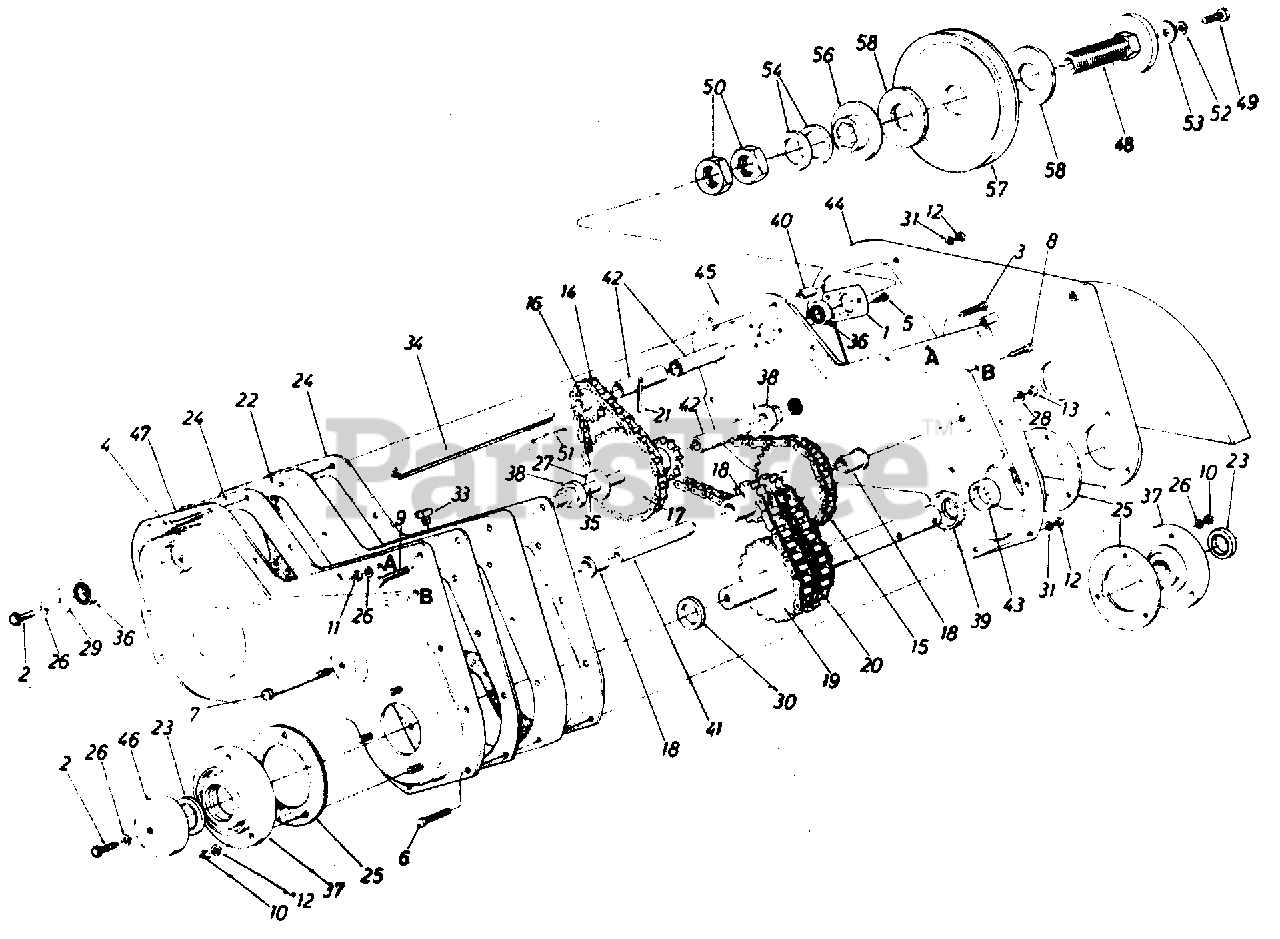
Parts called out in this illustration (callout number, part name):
1	Bearing Housing 1-3/8" Dia.
2	Hex Bolt 5/16-18 x .88"
3	Hex Bolt 5/16-18 x 1.5" Lg.
4	Hex Bolt 1/4-20 x 2.75" Lg.
5	Hex S-Tap Scr. 1/4-20 x .5" Lg.
6	Hex Bolt 1/4-20 x 1.5" Lg.
7	Hex Bolt 3/8-16 x 4.5" Lg.
8	Hex Scr. 1/4-20 x 1.5" Lg.
9	Hex TT-Tap Scr. 5/16-18 x 1.75"
10	Hex L-Nut 5/16-18 Thd.
11	Hex Nut 5/16-18 Thd.
12	Hex Nut 1/4-20 Thd.
13	Hex Nut 3/8-16 Thd.
14	#41 Chain 1/2" Pitch x 34 Links - Endless
15	#42 Chain 1/2" Pitch x 48 Links - Endless
16	Sprocket 10 Tooth .5" Pitch
17	10 & 28 Teeth Sprocket Ass'y.
18	8-2 & 28 Sprocket Sleeve Ass'y.
19	18-2 Sprocket Shaft Ass'y.
20	#50-2 Chain 5/8" Pitch x 28 Links - Endless
21	Spring Pin Spir. 1/4" Dia. x 1.5" Lg.
22	Spacer Block - Tiller Housing
23	Oil Seal 1-1/4" Dia.
24	Gasket for Tiller Housing
25	Gasket for Brg. Housing
26	L-Wash. 5/16" I.D.
27	Fl-Wash..64" I.D. x 1.24" O.D.
28	L-Wash. 3/8" I.D.- H.D.
29	Fl-Wash..344" I.D. x 1.125"
30	Special Washer
31	L-Wash. 1/4" I.D."
33	Vent Plug
34	Jack Shaft .525" I.D. x 7.78"
35	Sprocket Shaft .63" Dia. x 5"
36	Ball Brg..62" I.D. x 1.38" O.D.
37	Bearing Housing - 1-1/4"
38	Hex Flange Brg.
39	Spacer 1.25" I.D. x 2.0" O.D.
40	Spacer .9" Lg.
41	Spacer 3.44" Lg.
42	Spacer .62" x
43	Spacer .5" Lg.
46	Dust Cap
49	Hex Bolt 5/16-18 x 1.25" Lg. Grade 5
50	Hex Jam Nut 1.0-14 x 28 Thd.
51	Sq. Key 3/16 x 1.5" Lg.
52	L-Wash. 5/16" I.D.
53	Fl-Wash..344" I.D. x 1.125"
54	Bell-Wash. 1.0" I.D. x 2.0"
56	Floating Disc 3-1/4" O.D.
57	5/8 V-Pulley 1.5" I.D. x 6.5"
58	Friction Pad 3-1/4" O.D. x 1-3/8" I.D.
